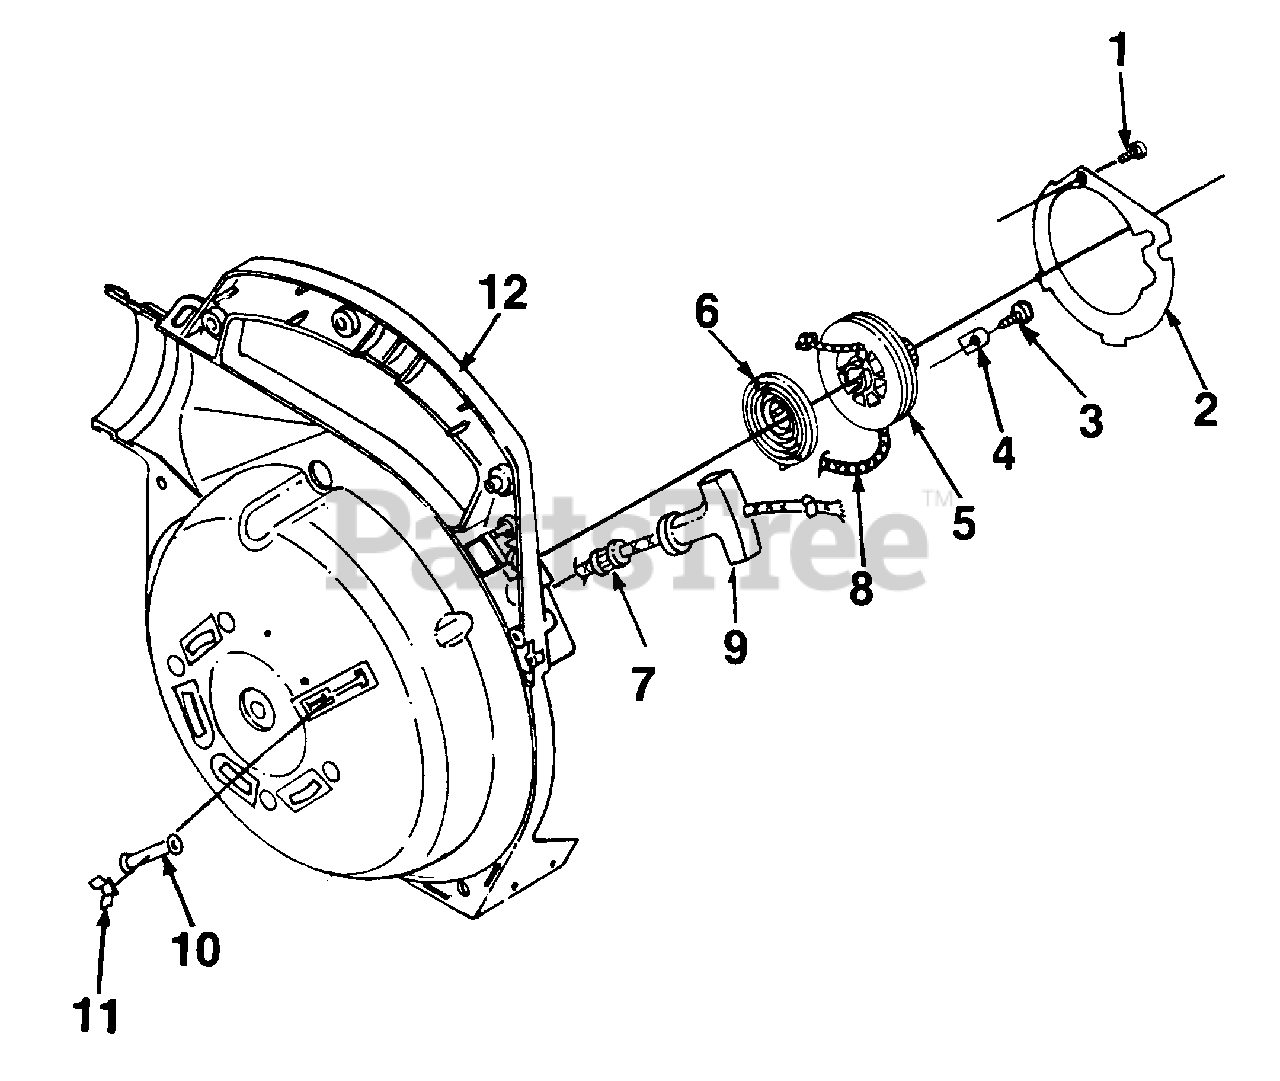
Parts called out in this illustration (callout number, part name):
1	SCREW - Thread Forming (#6-19 x 3/4 lg.)
2	PLATE - Rotor
3	SCREW - Thd. forming 10 x 1/2
4	BRACKET - Retaining
5	PULLEY - Starter
6	SPRING & CONTAINER
7	BUSHING - Starter
8	ROPE - Starter 46"
9	GRIP - Starter rope
10	BUSHING - Starter rope
11	CLIP - Retainer
12	HOUSING - Volute (inner)
